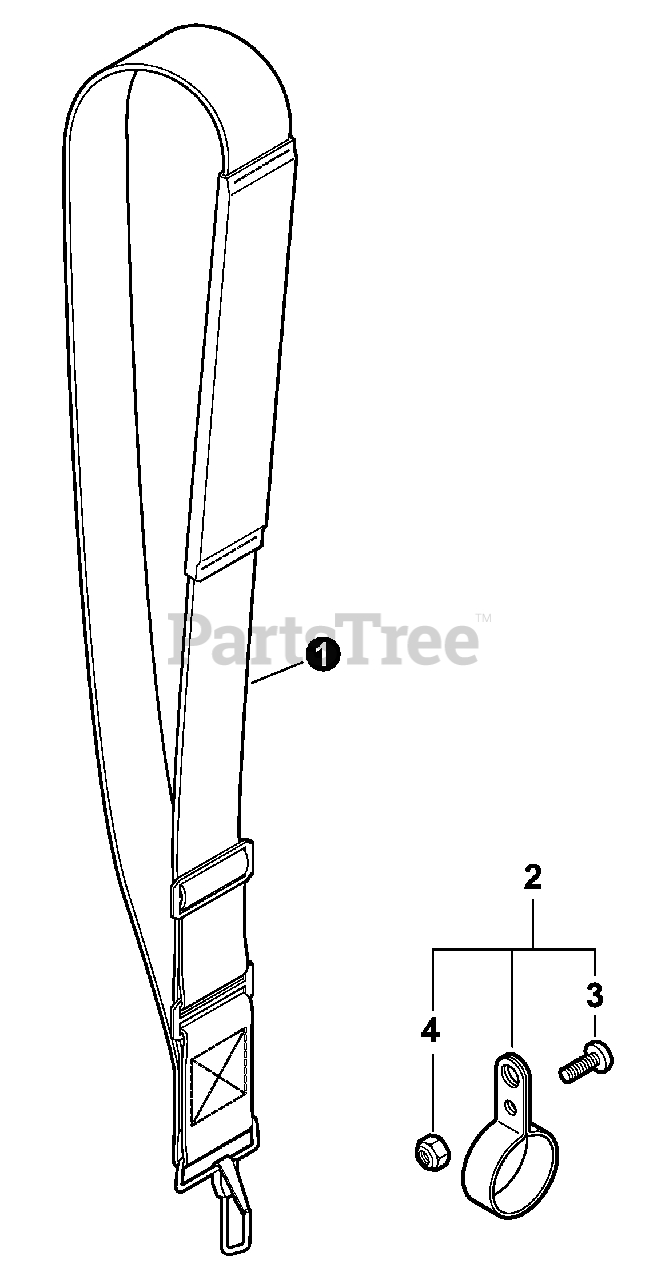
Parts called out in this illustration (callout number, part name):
1	STRAP ASSY, SHOULDER
2	HANGER KIT
3	BOLT, TORX 5×10
4	NUT, M5×8 NYLON INSERT
